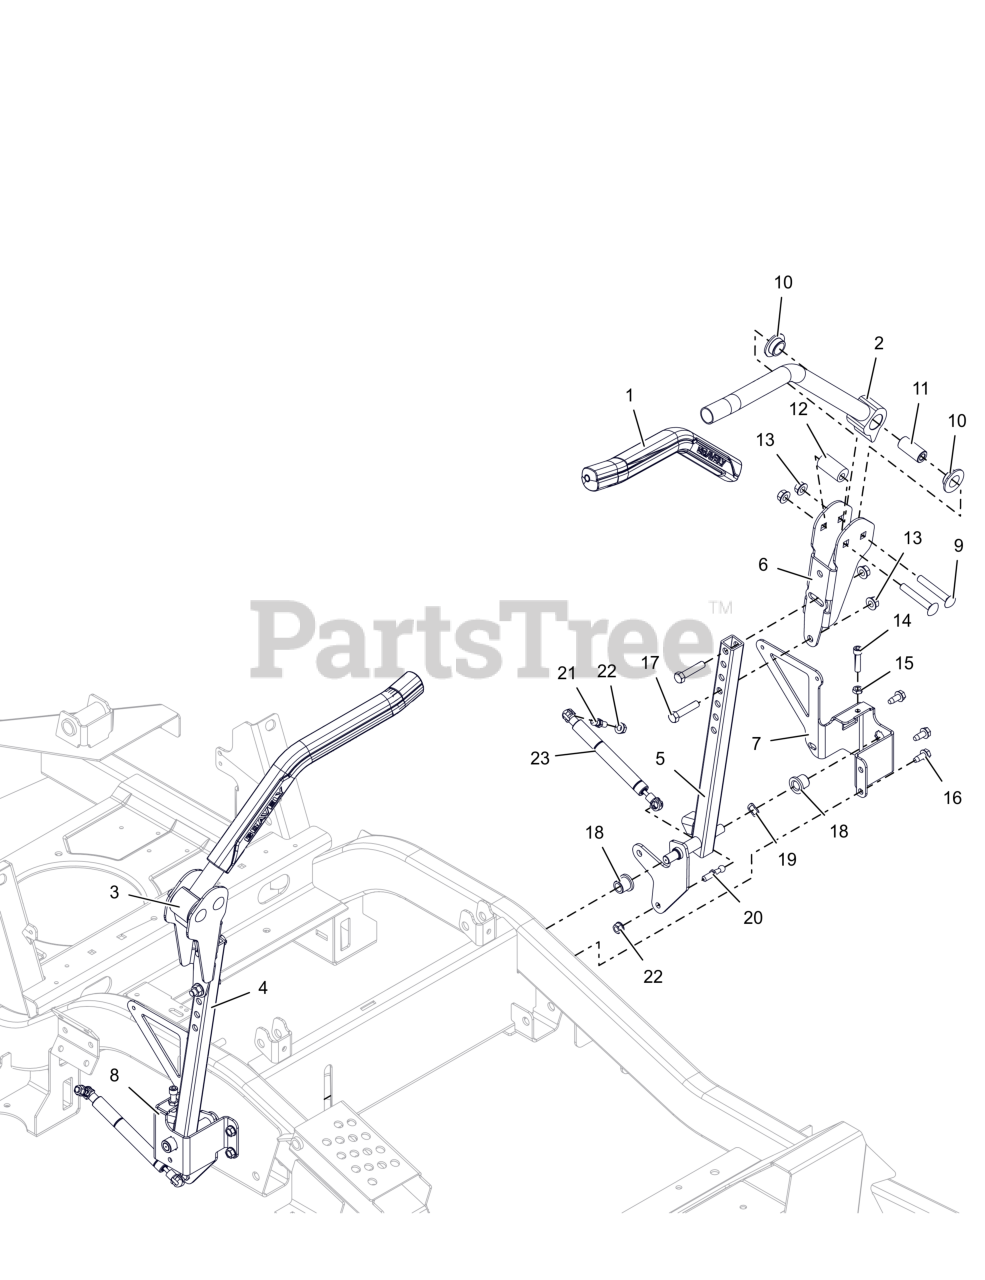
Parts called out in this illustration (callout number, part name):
1	GRIP- HANDLEBAR GRAVELY
2	WLDMT, CONTROL HANDLE (RED)
3	WLDMT, CONTROL HANDLE (RED)
4	WLDMT, STEERING RH (RED)
5	WLDMT, STEERING -LH (RED)
6	BRKT, ADJ UPPER CONTROL ARM (RED)
7	BRKT, STEERING ARM MOUNTING -LH (RED)
8	BRKT, STEERING ARM MOUNTING- RH (RED)
9	BLT, RHSSN.38-16X2.50 G5 ZCC
10	BSHG, FLANGED .762 X 1.48 X .44 IGLIDER
11	SPACER, STEERING ARM
12	BSHG, ECCENTRIC.406X.875X1.625
13	NUT-LK-TOP-FLG .38-16 ZC120
14	SCR, SKH .312-18X1.25 GR8 ZC120
15	NUT-JAM .312-18 G2 ZCC
16	SCR,TAP .312-18X.75 HWH TR ZCC
17	BLT, HEX .38-16X1.75 G5 ZCC
18	BHSG-FLG .500X.750X.750X.125
19	WAVE WASHER .531X.781X.125FH
20	STUD-BALL-THREADED
21	STUD- BALL
22	NUT,LK-CTR-FLG .31-18 GF ZCC
